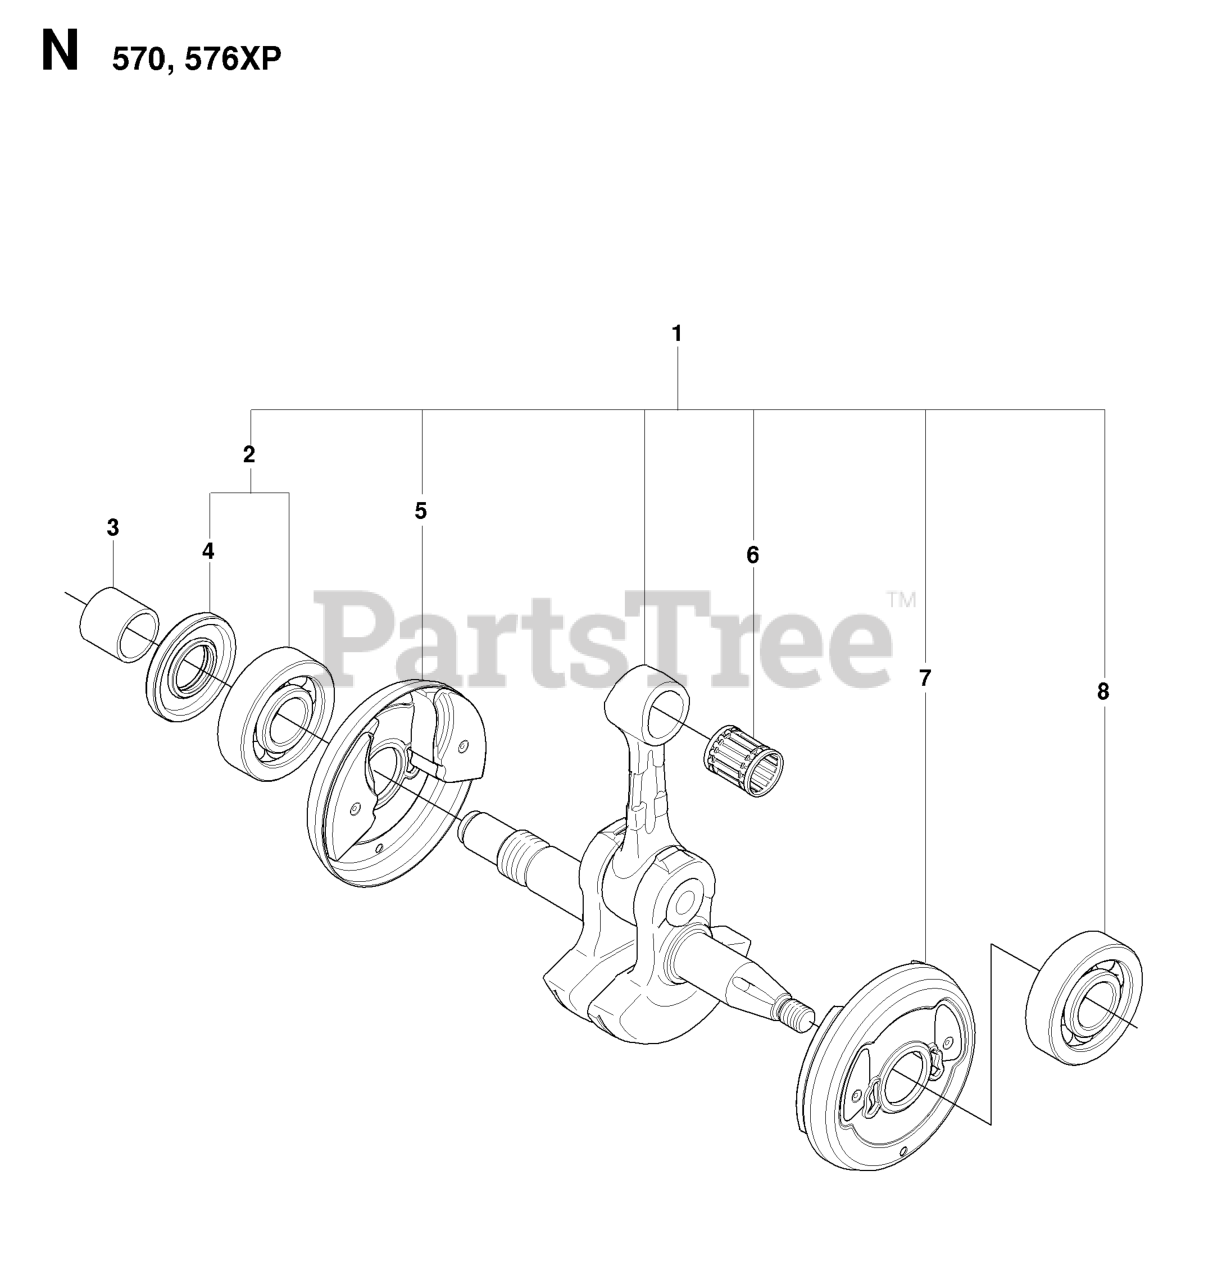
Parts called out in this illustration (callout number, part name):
1	RP CRANKSHAFT ASSY
2	%BALL BEARING
4	RADIAL SEAL
6	SUPPORT BUSHING
8	BALL BEARING
